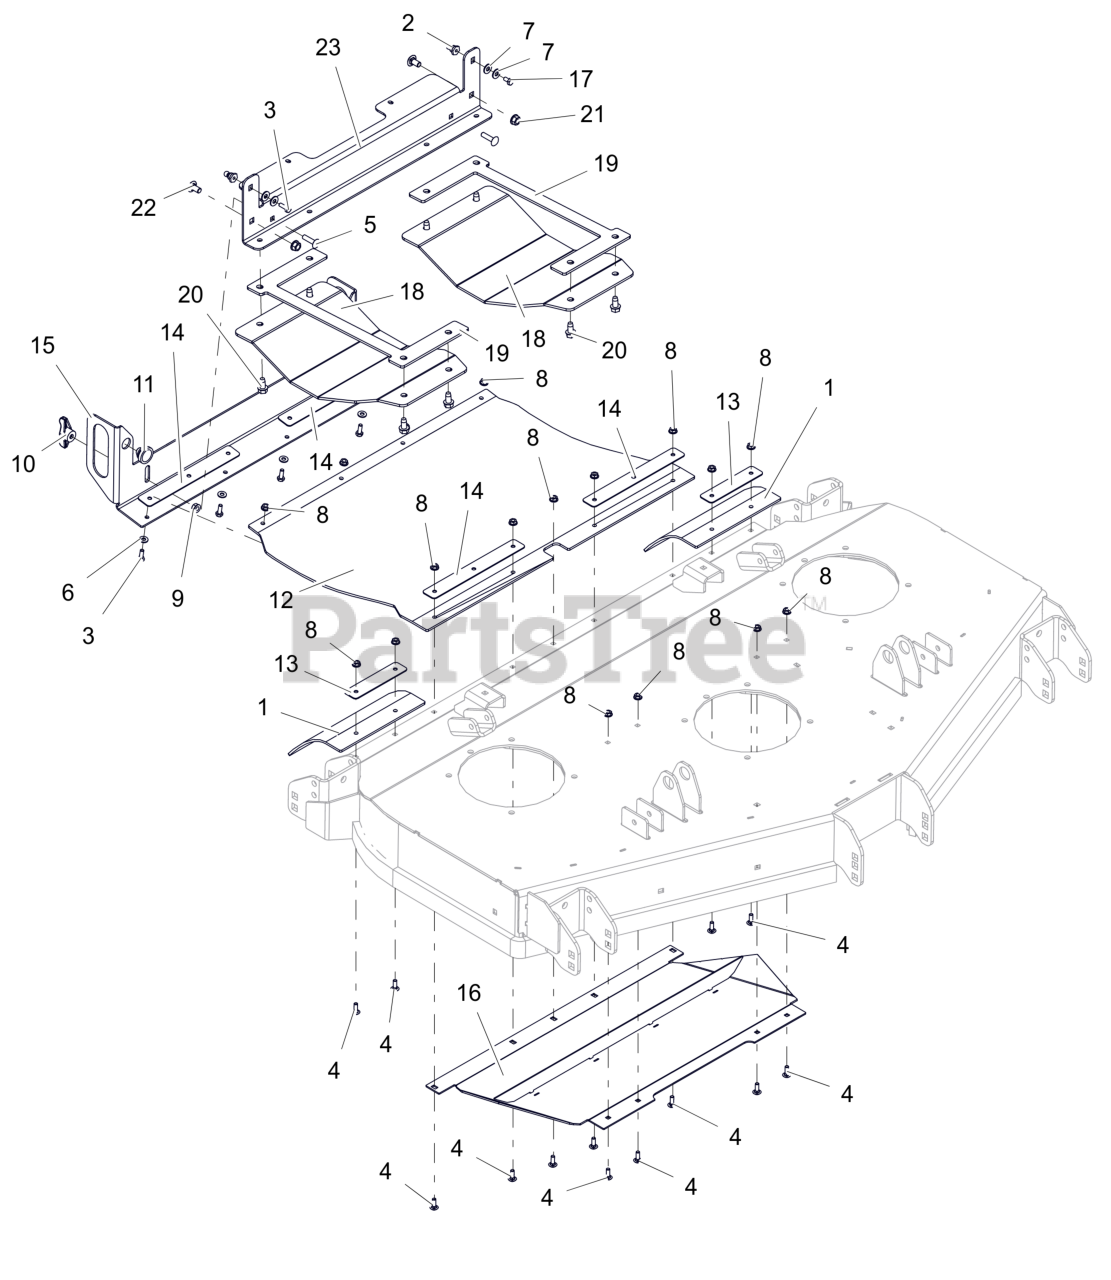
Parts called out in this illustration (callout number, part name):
1	FLAP, REAR DISCHARGE 52" TIRE
2	STUD, BALL FEMALE .250-20 THREAD
3	BLT, HEX .25-20X.75 G5 ZCC
4	BLT, RHSN .25-20X.750 G5 ZCC
5	BLT, RHSSN.31-18X1.25 G5 ZCC
6	WSHR,FLT .281X.625X.065 ZCC
7	WSHR, FLT .312X.734X.065 ZCC
8	NUT-LK-CTR-FLG .25-20 ZC120
9	NUT,LK-CTR-FLG .31-18 GF ZCC
10	KNOB,WING .31-18 UNC NYL/TALC
11	COUPLING, RUBBER PUSH-IN
12	CHUTE, REAR DISCHARGE
13	PLATE, 52" TIRE CHUTE MTG (BLACK)
14	PLATE, CHUTE MTG (BLACK)
15	HANDLE, CHUTE MOUNTING (ORANGE)
16	WLDMT, DEFLECTOR BAFFLE (ORANGE)
17	BLT,HEX .25-20X.50 G5 ZCC
18	PLATE, SKID (BLACK)
19	PLATE, SKID TENSION (BLACK)
20	SCR,TAP .375-16X.75 HWH TR ZCC
21	NUT-LK-CTR-FLG .375-16 GF ZCC
22	BLT, RHSSN .38-16X.75 G5 ZCC
23	BRKT, SKID PLATE MTG. (ORANGE)
